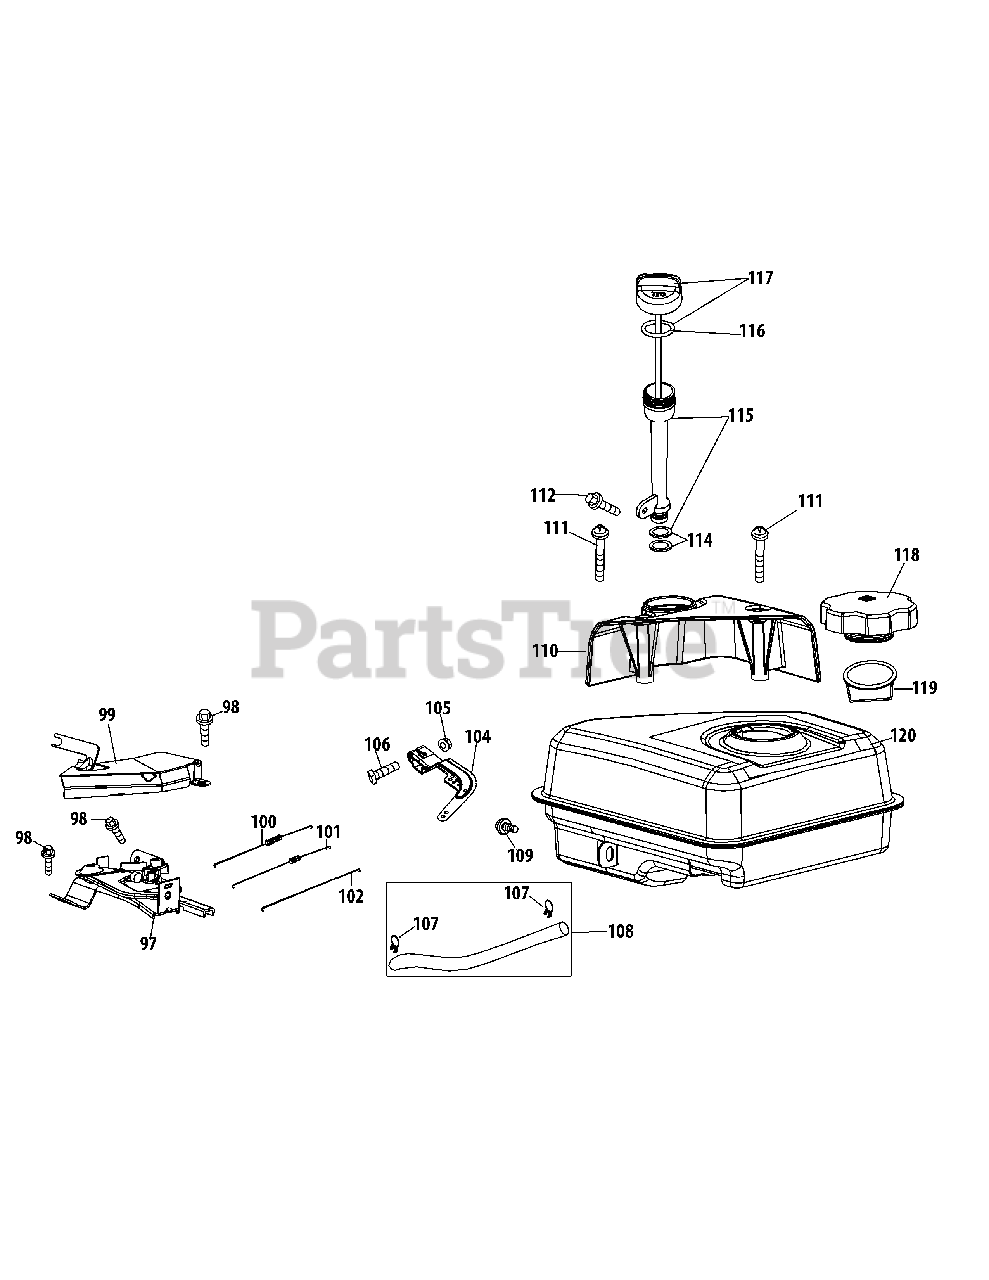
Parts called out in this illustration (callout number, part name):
97	Primer Bracket
98	Bolt M6×12
99	Governor System Shield
100	Governor Spring
101	Throttle Linkage Spring
102	Throttle Linkage
104	Governor Arm
105	Nut M6
106	Governor Arm Bolt
107	Fuel Hose Clamp
108	Fuel Hose
109	Bolt M6×12
110	Dipstick Decoration Cover
112	Bolt M6×12
114	Oil Fill Tube O-Ring
115	Oil Fill Tube
116	Oil Fill Tube O-Ring
117	Dipstick Assembly
118	Fuel Cap Assembly
119	Fuel Level Indicator
120	Fuel Tank Assembly
